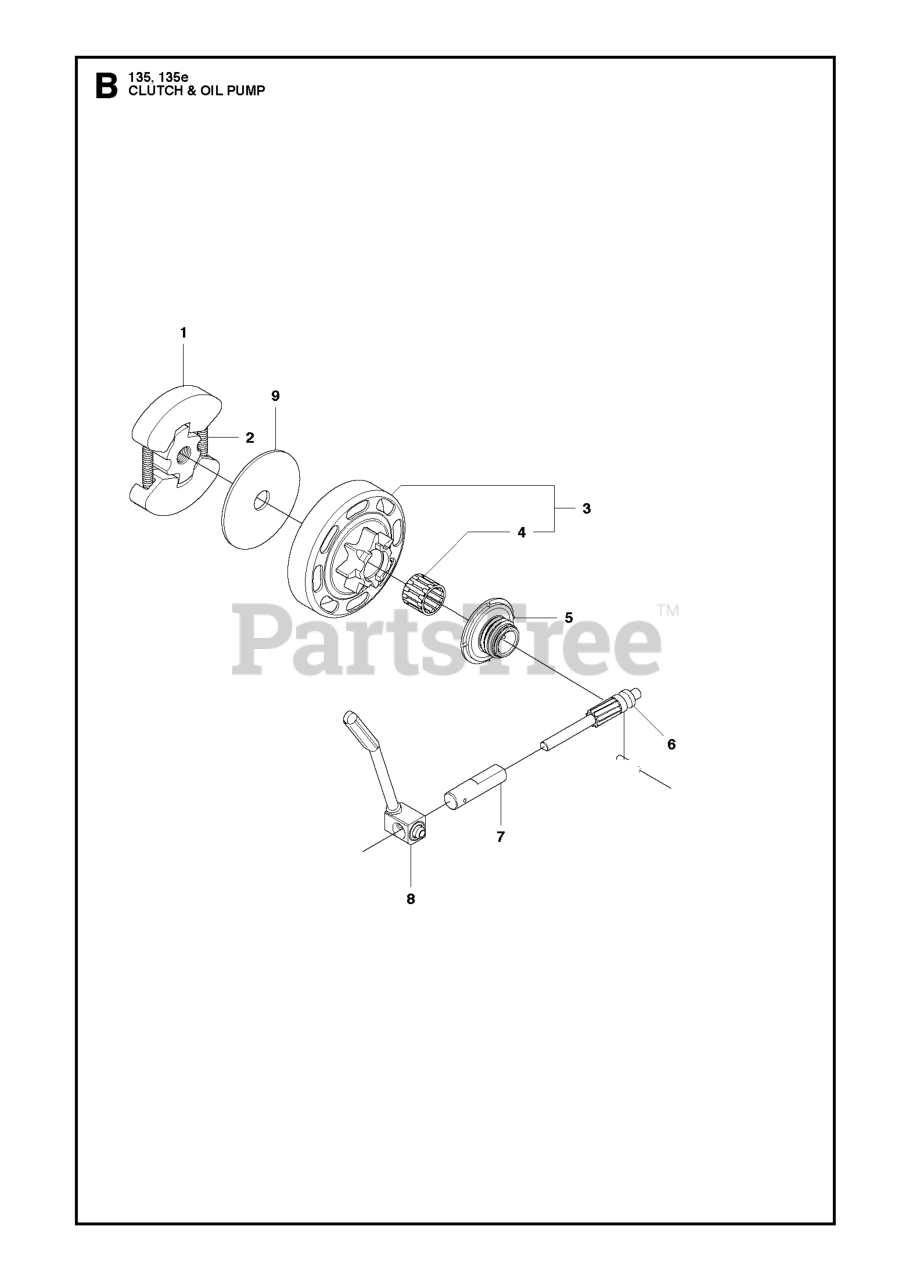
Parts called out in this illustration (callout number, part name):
1	CLUTCH ASSEMBLY
2	CLUTCH SPRING 36/41
3	CLUTCH DRUM ASSY
4	SUPPORT BUSHING
5	ASSY WORM GEAR
6	PISTON PUMP
7	PUMP CYLINDER
8	HOSES
9	FRICTION DISC,CLUTCH 36/41
